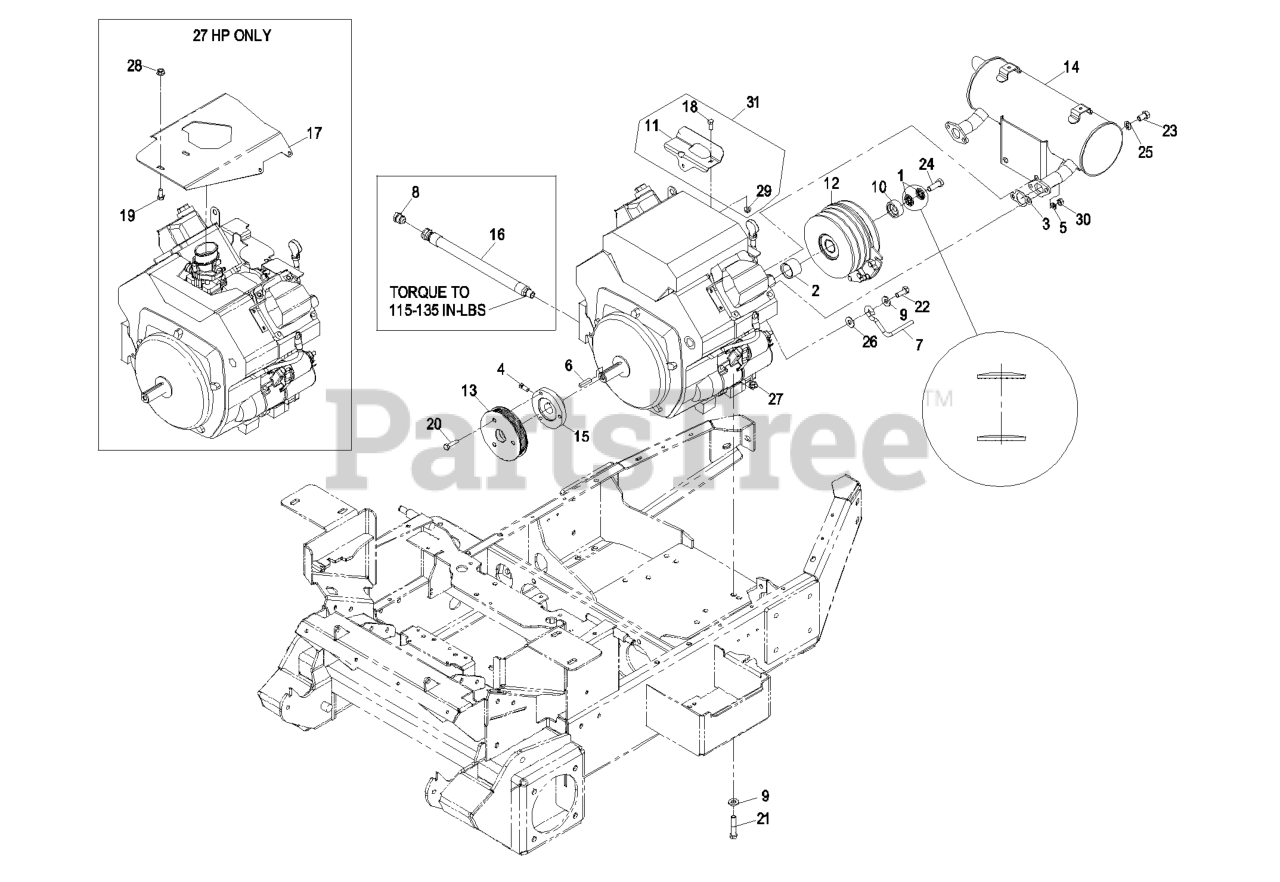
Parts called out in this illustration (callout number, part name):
1	WASHER-SPRING
2	SPACER-CLUTCH
4	SCREW-SET
5	WASHER-LOCK
6	KEY-SQUARE
7	ROD-BELT
8	PLUG
9	WASHER-BELLEVILLE
10	KEEPER-CLUTCH
11	CABLE HEAT SHIELD KIT
12	CLUTCH KIT
13	SHEAVE, 5K 4.63
14	KIT,MUFFLER KOHLER
15	HUB,ADAPTER (PLTD)
17	BRACKET, AIRCLNR FMZ-AC
18	SCREW-HH
19	SCREW-HH
20	SCREW-HH
21	SCREW-HH
22	SCREW-HH
23	SCREW-HH
24	SCREW-HH
25	SCREW-HH
26	WASHER-FLAT
27	NUT-HHF, WHIZ
28	NUT-HF
30	NUT-HEX
31	CABLE HEAT SHIELD KIT
